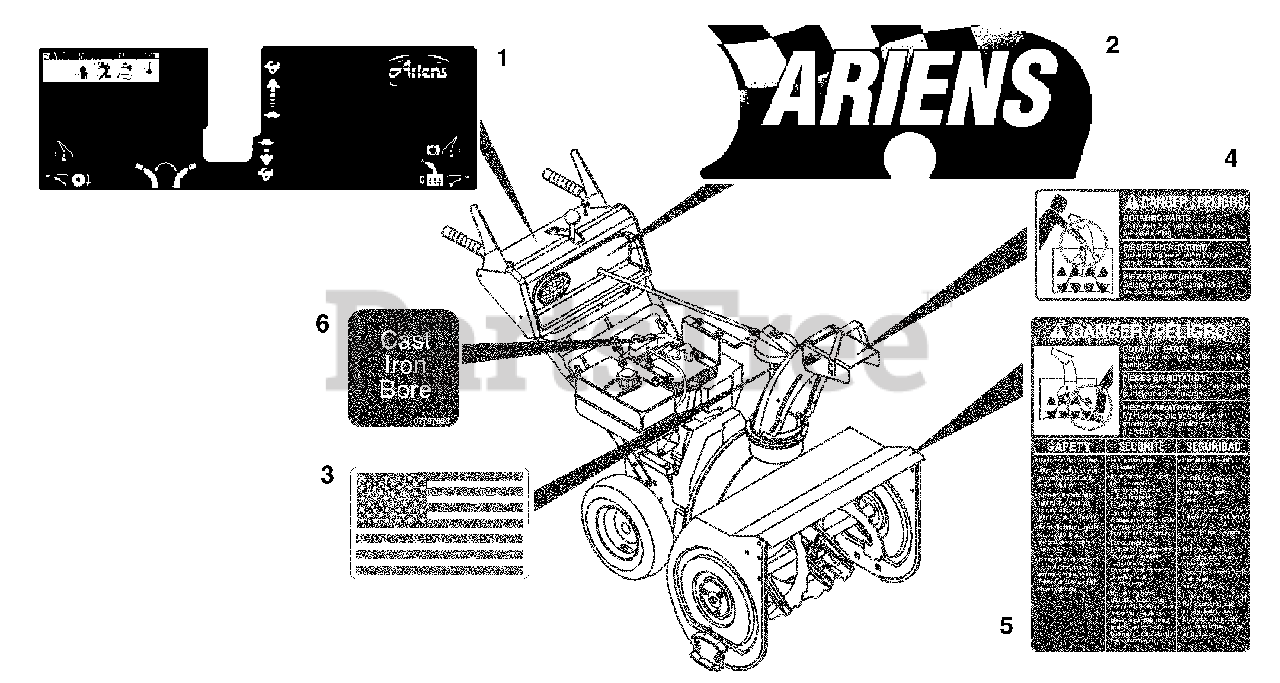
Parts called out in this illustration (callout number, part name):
1	DECAL- CONTROL
2	DECAL, FRT PANEL - 8524
3	DECAL, AMERICAN FLAG
4	DECAL, DANGER - ROT. PARTS
5	DECAL, DANGER
6	DECAL - CAST IRON BORE
